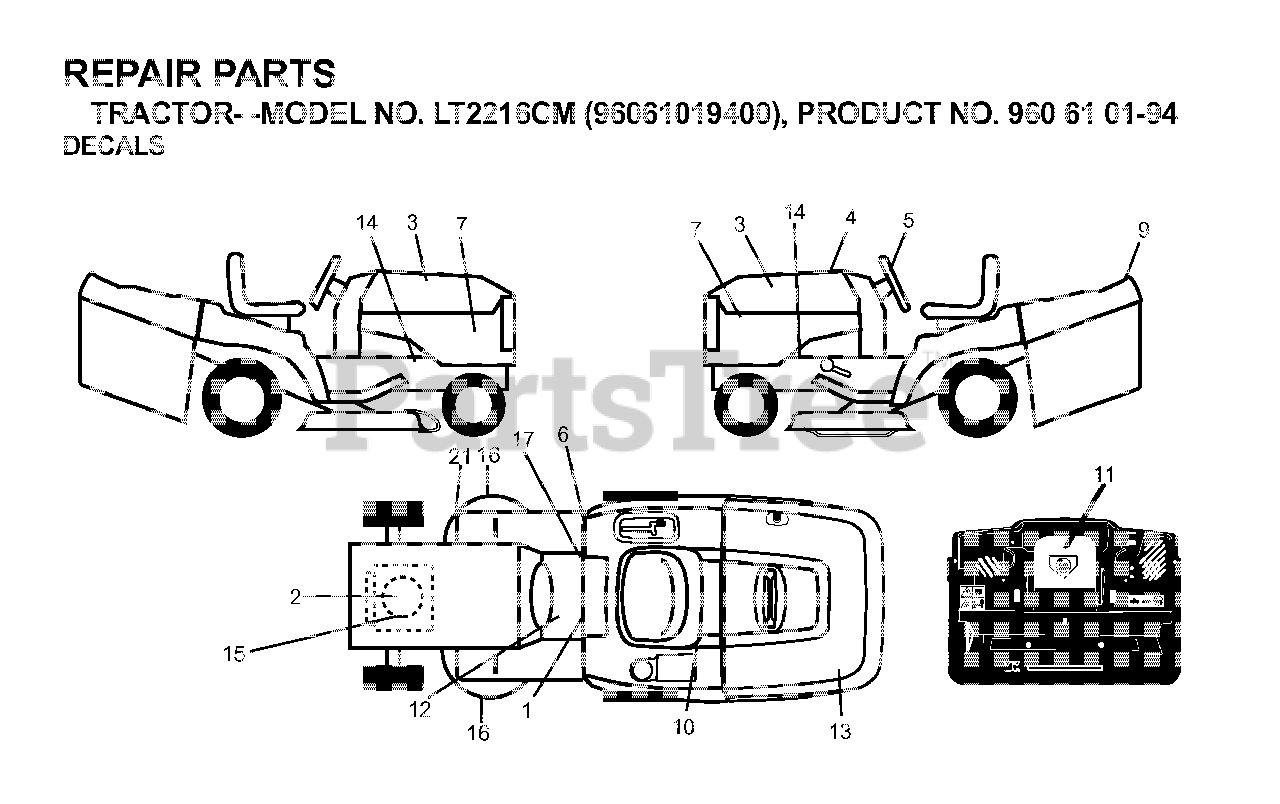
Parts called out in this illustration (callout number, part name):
8	DECAL FENDER
10	DECAL BTRY SYMBOLS
11	DECAL.INTERNATIONL.CUTFINGER
17	DECAL PARK BRAKE
